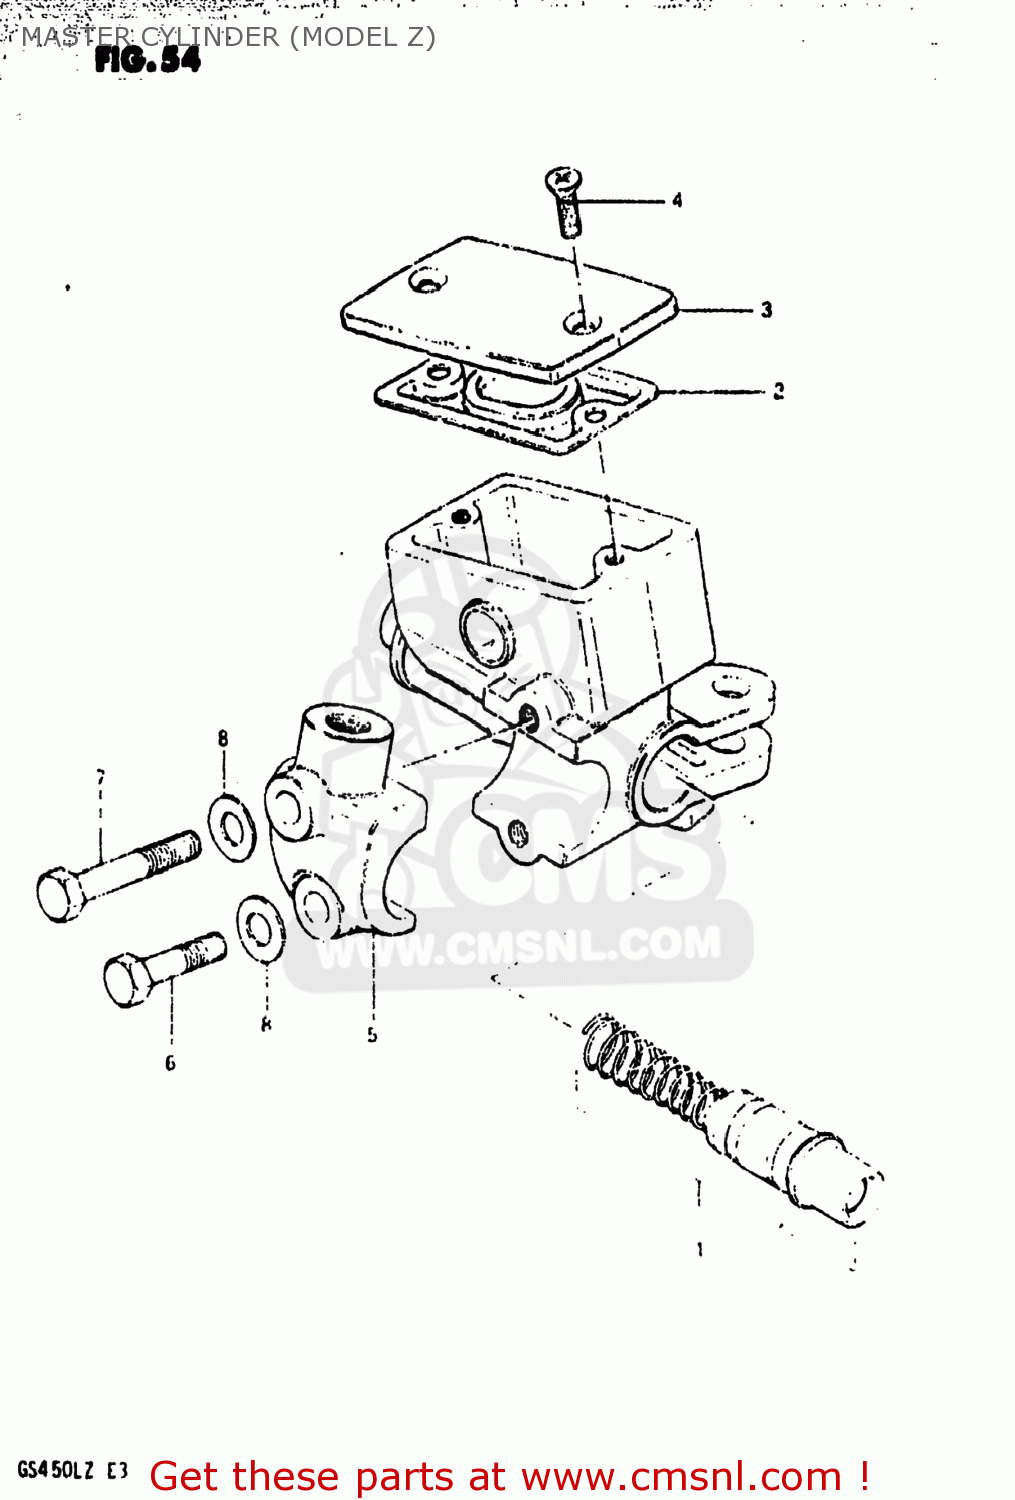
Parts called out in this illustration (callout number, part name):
1	PISTON & CUP SET
2	3
3	CAP
4	SCREW
5	HOLDER
6	BOLT
7	BOLT 6X40
8	LOCK WASHER
